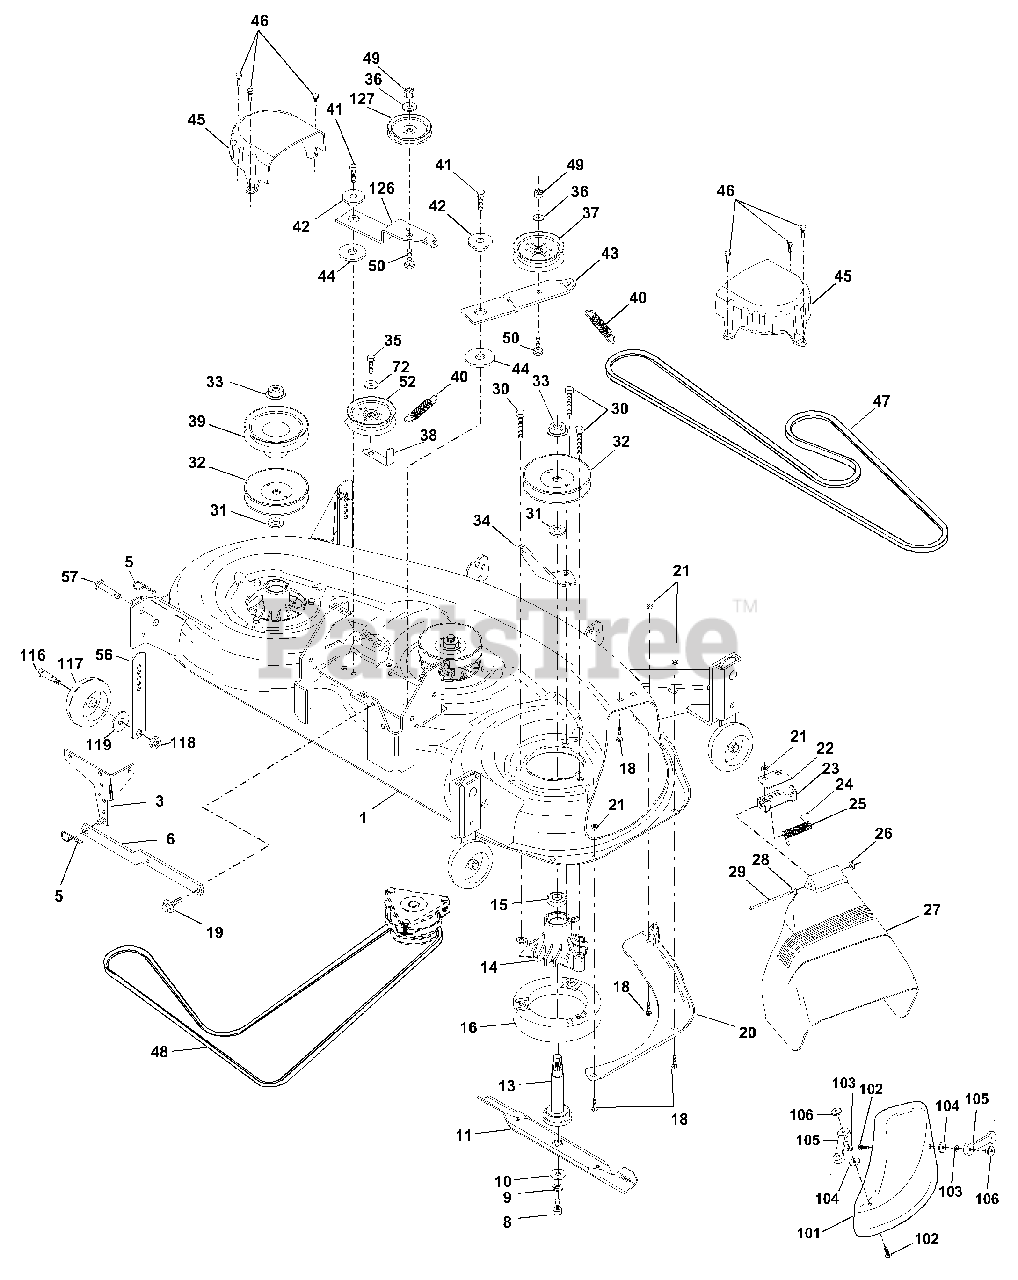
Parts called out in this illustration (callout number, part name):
1	Deck Weldment
3	Bracket Asm., Sway Bar
5	Retainer Spring
6	Arm, Suspension, Rear (Sway Bar)
8	Bolt, Patched 3/8-24 x 1-1/4 Gr. 8
9	Washer, Lock Hvy., Unplated 3/8
10	Washer, Hard Blade, Mower Vented
11	Blade, Hi Performance
11	Blade, Mulching
13	Shaft Asm. w/Lower Bearing
14	Housing, Mandrel
15	Bearing, Ball, Mandrel
16	Stripper, Mower Round
18	Bolt, Carriage 5/16-18 x 5/8
19	Bolt, Hex Head, Shoulder 5/16-18
20	Baffle, Vortex Mower 46"
21	Nut, Crownlock 5/16-18 UNC
22	Stiffiner, Bracket
23	Bracket, Deflector
24	Cap, Sleeve
25	Spring, Torsion, Deflector
26	Nut, Push
27	Deflector Clipping 46" Blk
28	Washer 11/32 x 5/8 x 16 Ga.
29	Rod, Hinge
30	Screw, Thdroll Wsh Hd
31	Washer, Spacer Mower Vented
32	Pulley, Mandrel
33	Nut, Flg. Top Lock
34	Anchor, Spring Deck 46"
35	Screw, Thdroll 3/8-16 x 1-3/4 Tytt
36	Washer 13/32 x 13/16 x 16 Ga.
37	Pulley, Idler, Flat
38	Keeper, Belt, Idler
39	Pulley, Idler, Driven
40	Spring, Secondary 44/46/50 Vent
41	Screw, 3/8-16 x 1-1/4 Tytt
42	Spacer, Retainer
43	Arm, Idler Secondary
44	Washer,Hardened
45	Cover, Mandrel Deck
46	Screw, Thdroll. 1/4-20 x 5/8
47	V-Belt, Mower, Secondary
48	V-Belt, Mower, Primary
49	Nut, Crownlock 3/8-16 UNC
50	Bolt, Carriage 3/8-16 x 1-1/2 Gr. 5
52	Pulley Idler 46 Pri Drive
56	Bar Adjusting Guage Wheel
57	Pin Head Rivet
72	Washer 13/32 x 1 x 16 Ga.
101	Cover Mulcher
102	Screw Pan Head Phillip 10-24 x 5/8
103	Washer Lock #10
104	Washer #10
105	Latch Asm Mulch/Bagger
106	Nut Weld
116	Bolt, Shoulder
117	Gauge Wheel, Wide
118	Nut, Centerlock 3/8-16 UNC
119	Washer 3/8 x 7/8 x 14 Ga.
126	Arm, Idler, Primary Deck 46"
127	Pulley Idler V-Gr. Plated 4.25
